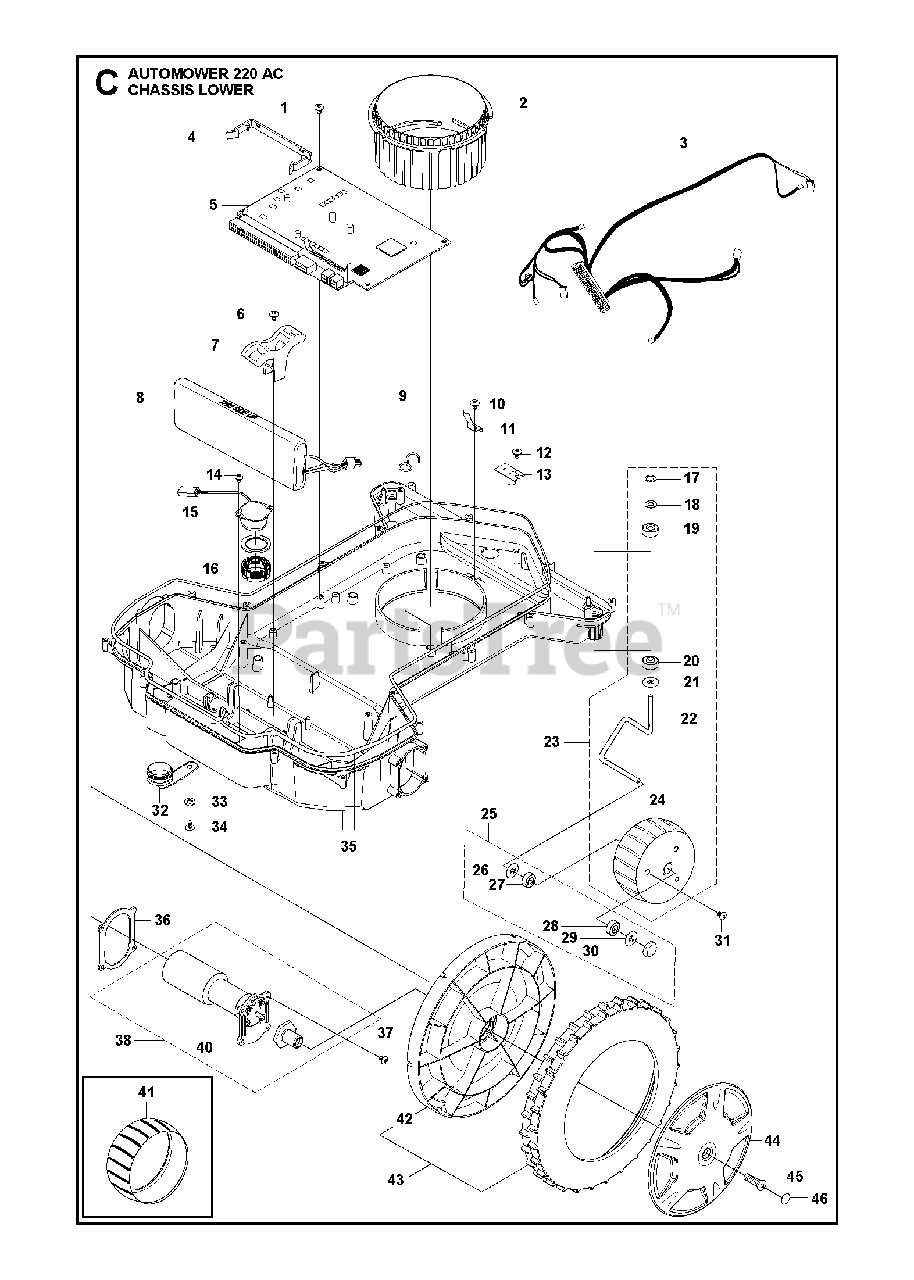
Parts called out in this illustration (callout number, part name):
1	SCREW SILVER 10MM
2	CUTTING HEIGHT NUT
3	MAIN WIRING
4	CLIP MAIN CONNECTOR
4	CLIP MAIN CONNECTOR 50PCS
5	PRINTED CIRCUIT ASSY AM220
6	SCREW 14MM
8	BATTERY
12	SCREW SILVER 10MM
13	PRINTED CIRCUIT ASSY
16	NUT BUZZER
17	LOCK WASHER
18	WASHER 6.4X12X1.6 SS
19	BALL BEARING
20	BALL BEARING
21	WASHER
22	SPINDLE
23	KIT 6MM AXLE KIT - STANDARD WH
24	WHEEL, FRONT
25	BEARING KIT 6MM AXLE
26	WASHER
27	BALL BEARING
28	BALL BEARING
29	WASHER
30	COVER WASHER
31	SCREW ITXPANT PT 40 THREAD
32	PLUG SERVICE PLUG
34	SCREW 14MM
35	CHASSIS LOWER
38	WHEEL MOTOR W/GEARBOX
40	HUB
41	WHEEL RUBBER TYRE
42	WHEEL LOGO ADDED
43	GEAR WHEEL
46	COVER WASHER
